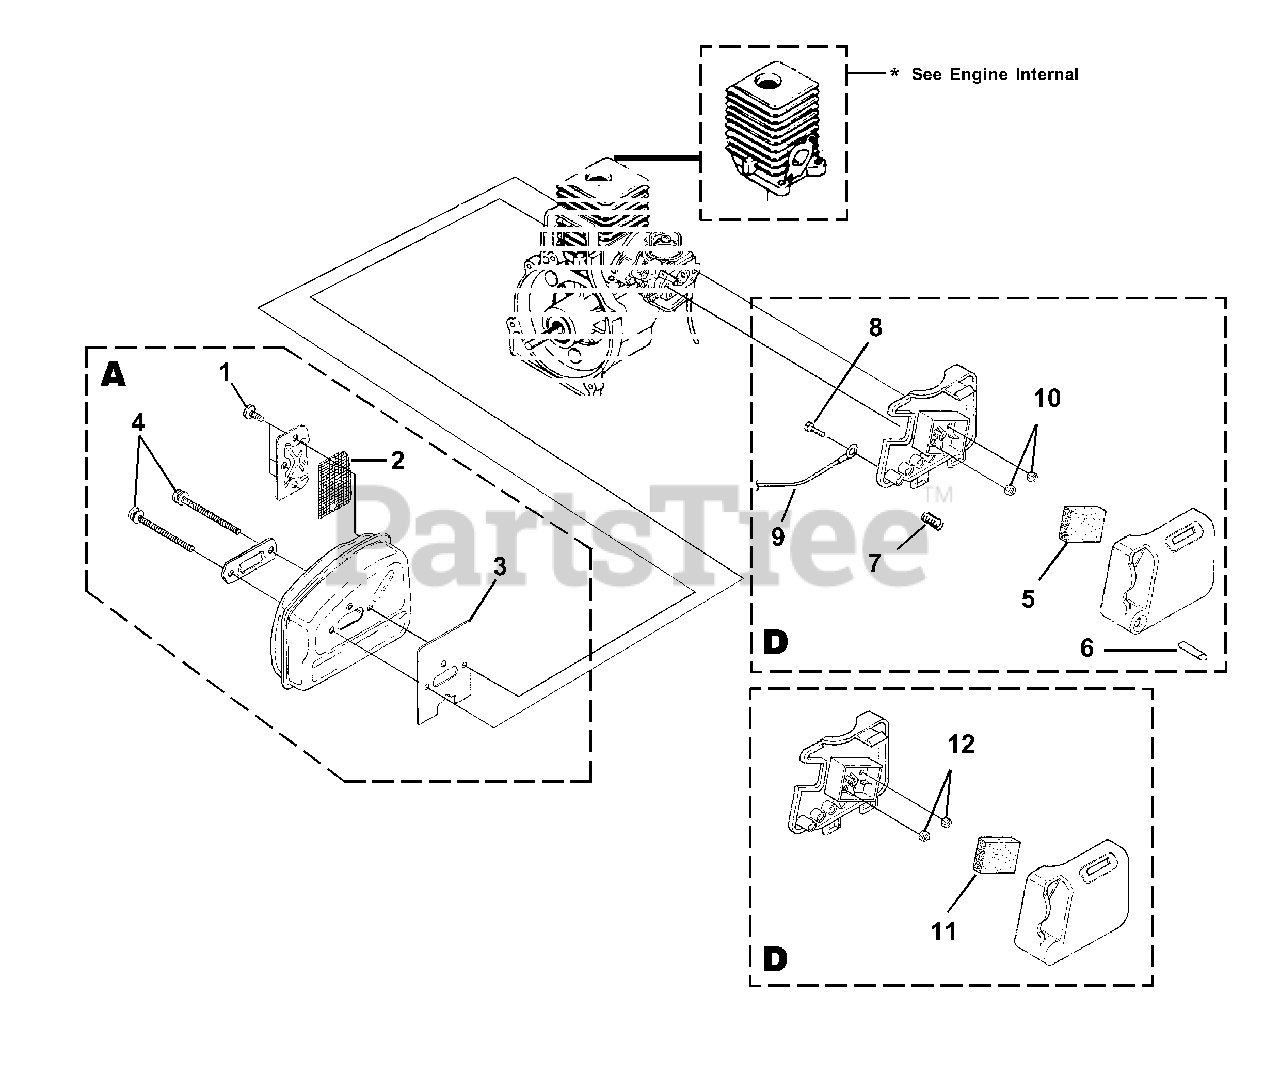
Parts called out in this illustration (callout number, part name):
1	SCREW, Taptite- (8-32 X 3/8")
2	SCREEN-Spark
3	GASKET-Muffler
4	SCREW, Truss Hd. - (10-24 X 2.188)
5	FILTER-Air
6	BUTTON-Switch
7	SPRING-Compression
8	SCREW-Thread Form (6-19 x 1/2")
9	LEAD-Electrical
10	NUT-Hex (10-24)
11	FILTER-Air
12	NUT-Hex (10-24)
A	MUFFLER ASSY.
D	AIR FILTER KIT (Non-Clutch)
D	AIR FILTER KIT (Clutch)
